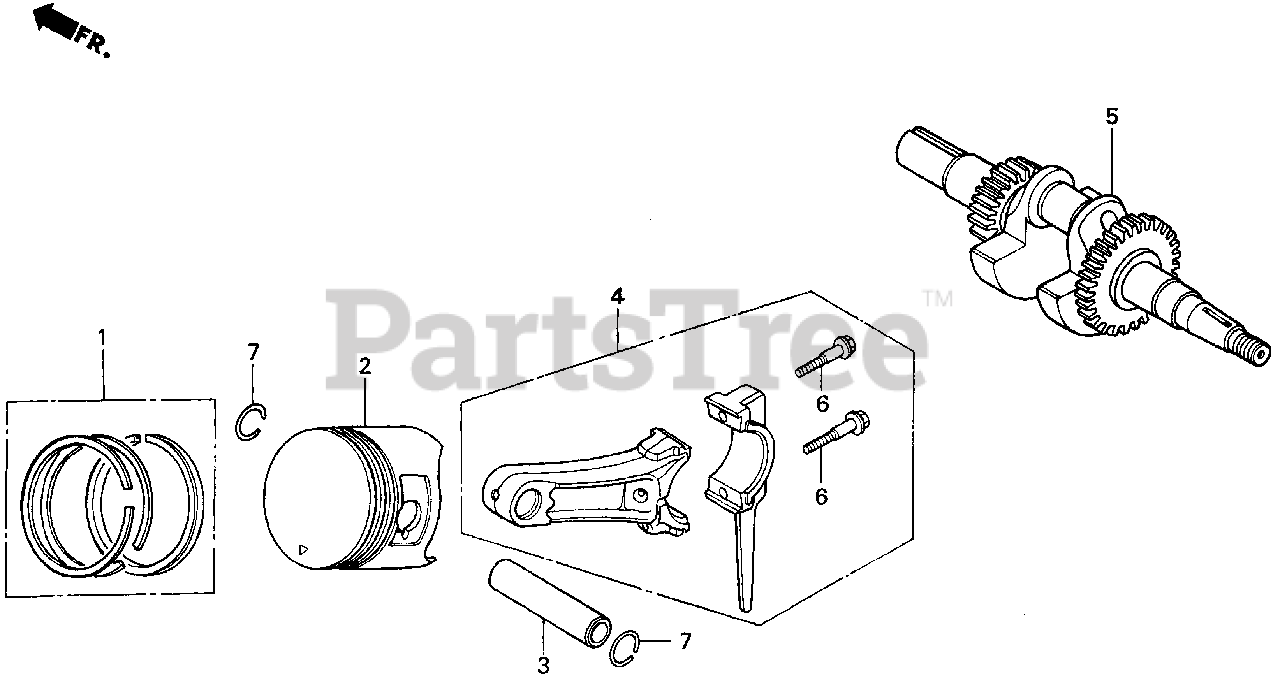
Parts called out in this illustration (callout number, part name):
1	RING SET, PISTON (STD) (TEIKOKU)
1	RING SET, PISTON (STD.) (NIPPON)
1	RING SET, PISTON (0.25) (TEIKOKU)
1	RING SET, PISTON (0.25) (NIPPON)
1	RING SET, PISTON (0.50) (TEIKOKU)
1	RING SET, PISTON (0.50) (NIPPON)
1	RING SET, PISTON (0.75) (TEIKOKU)
1	RING SET, PISTON (0.75) (NIPPON) (NOT AVAILABLE)
1	RING SET, PISTON (0.75) (NIPPON)
2	PISTON (STD)
2	PISTON (0.25)
2	PISTON (0.50)
2	PISTON (0.75)
3	PIN, PISTON
4	ROD ASSY., CONNECTING (0.25 LOWER SIZE)
4	ROD ASSY., CONNECTING (TH)
5	CRANKSHAFT
6	BOLT, CONNECTING ROD
7	CLIP, PISTON PIN (18MM)
